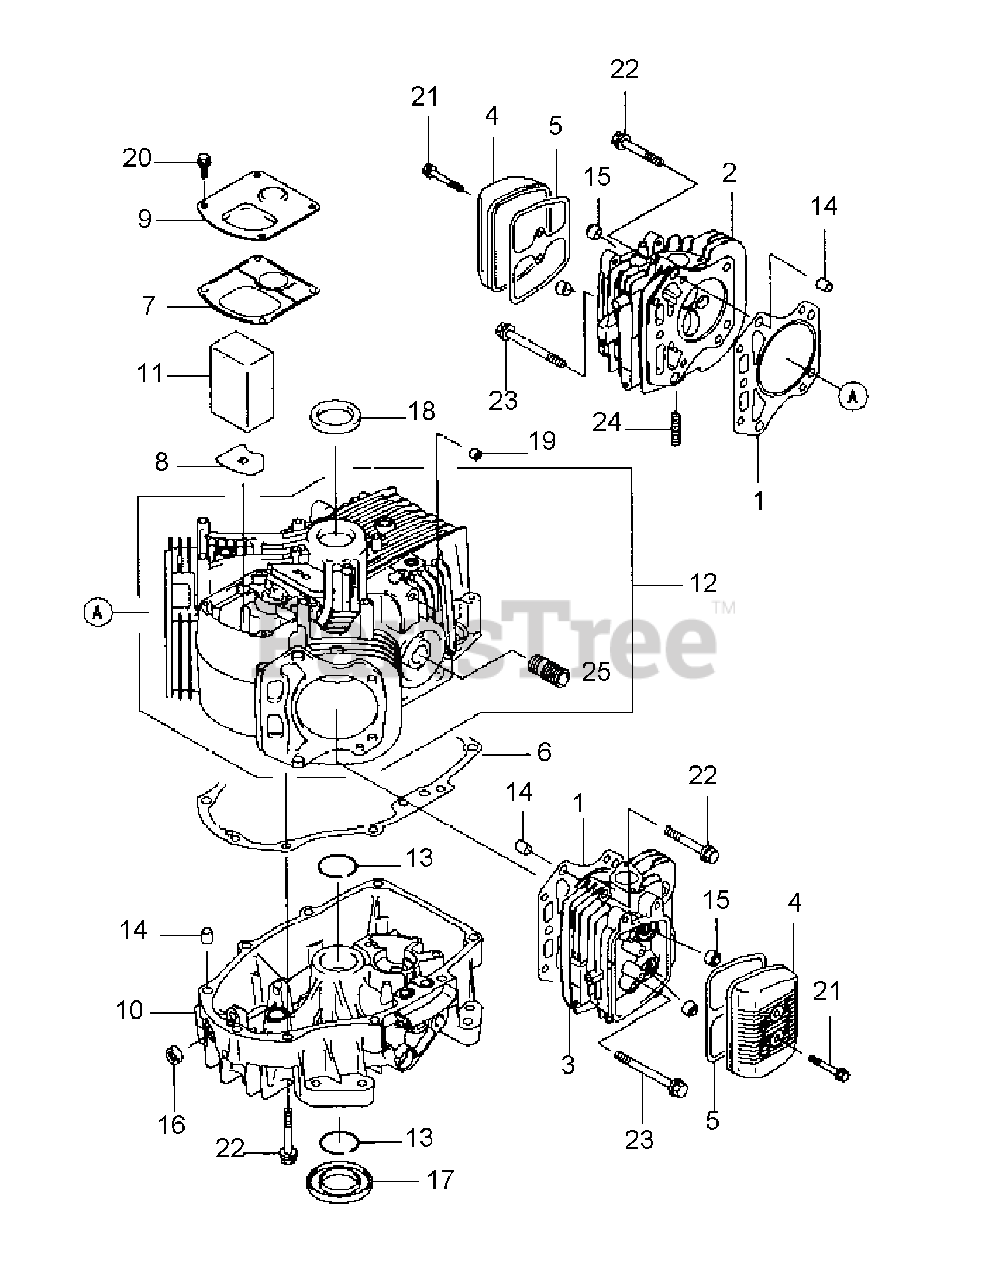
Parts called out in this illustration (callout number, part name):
2	HEAD-COMP-CYLINDER, #2
3	HEAD-COMP-CYLINDER, #1
5	GASKET, ROCKER CASE
7	GASKET, BREATHER
9	COVER
10	COVER-CRANKCASE
11	BREATHER ELEMENT
12	CRANKCASE-COMP
15	SEAL-OIL,RVC2 6X11X10.2
16	SEAL-OIL,SO 8X14X5 HS
17	SEAL-OIL,SD 35X62X8 L HS
18	SEAL-OIL, SD 35X48X8 R HS
20	BOLT-FLANGED
21	BOLT-FLANGED
22	BOLT-FLANGED
23	BOLT-FLANGED
